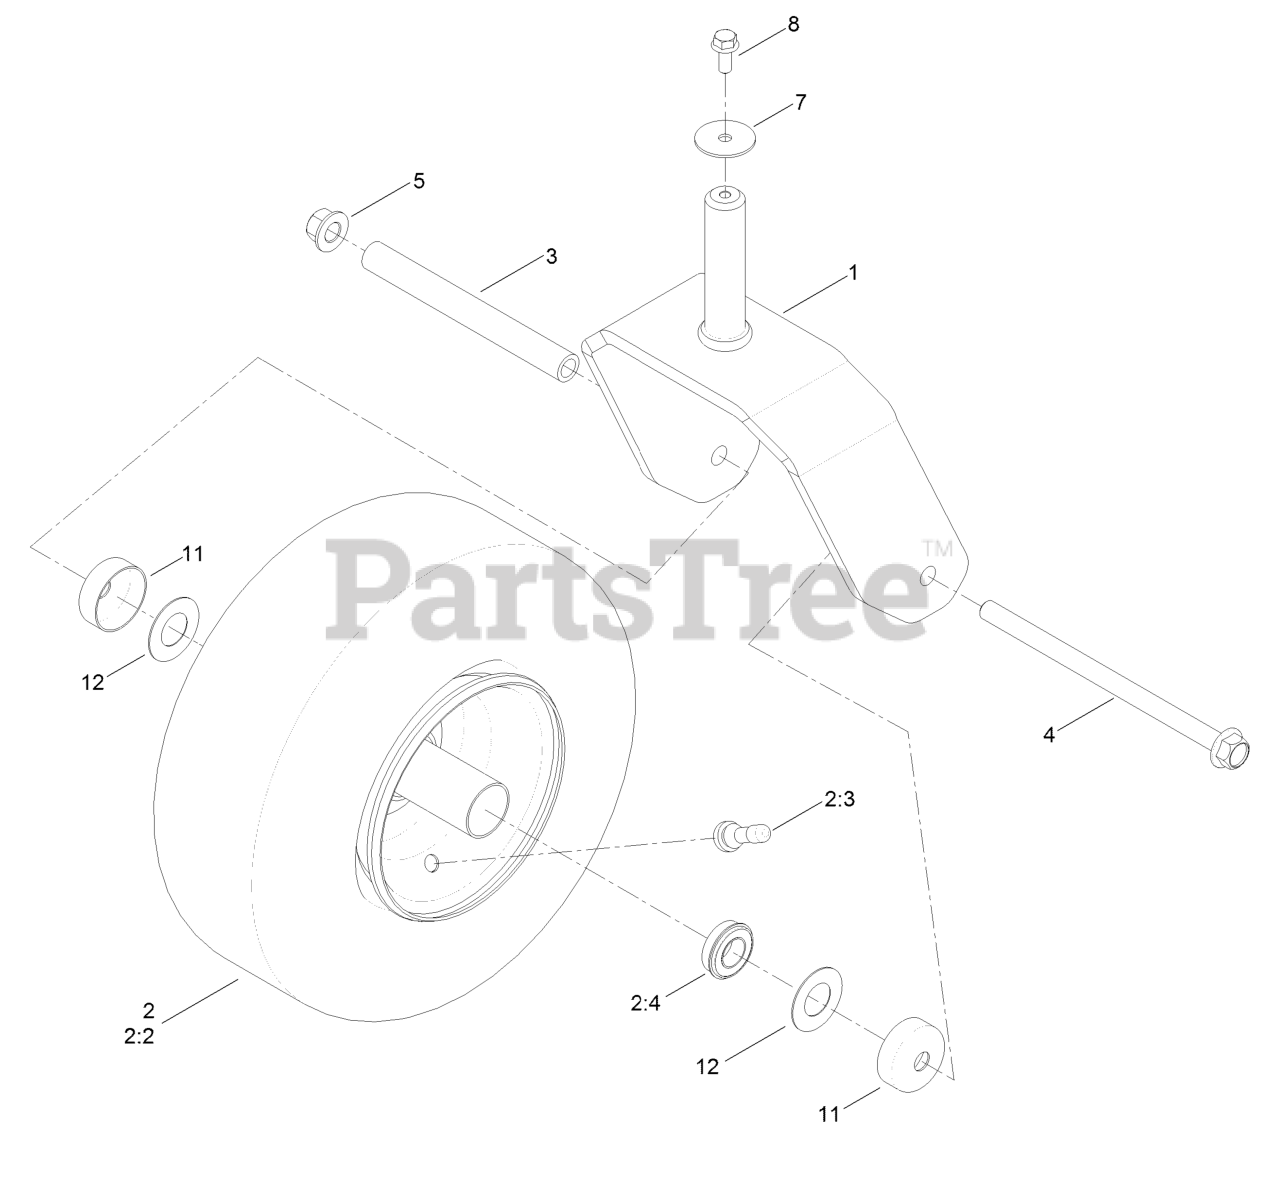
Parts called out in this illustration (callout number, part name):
2	Tire And Wheel ASM
2:3	Stem-Valve
2:4	Bearing
2:99	Tube-Inner
3	Spanner-Wheel
4	Screw-HHF
5	Nut-Lock
7	Washer-Flat
8	Screw-HHF
11	Guard-Seal
